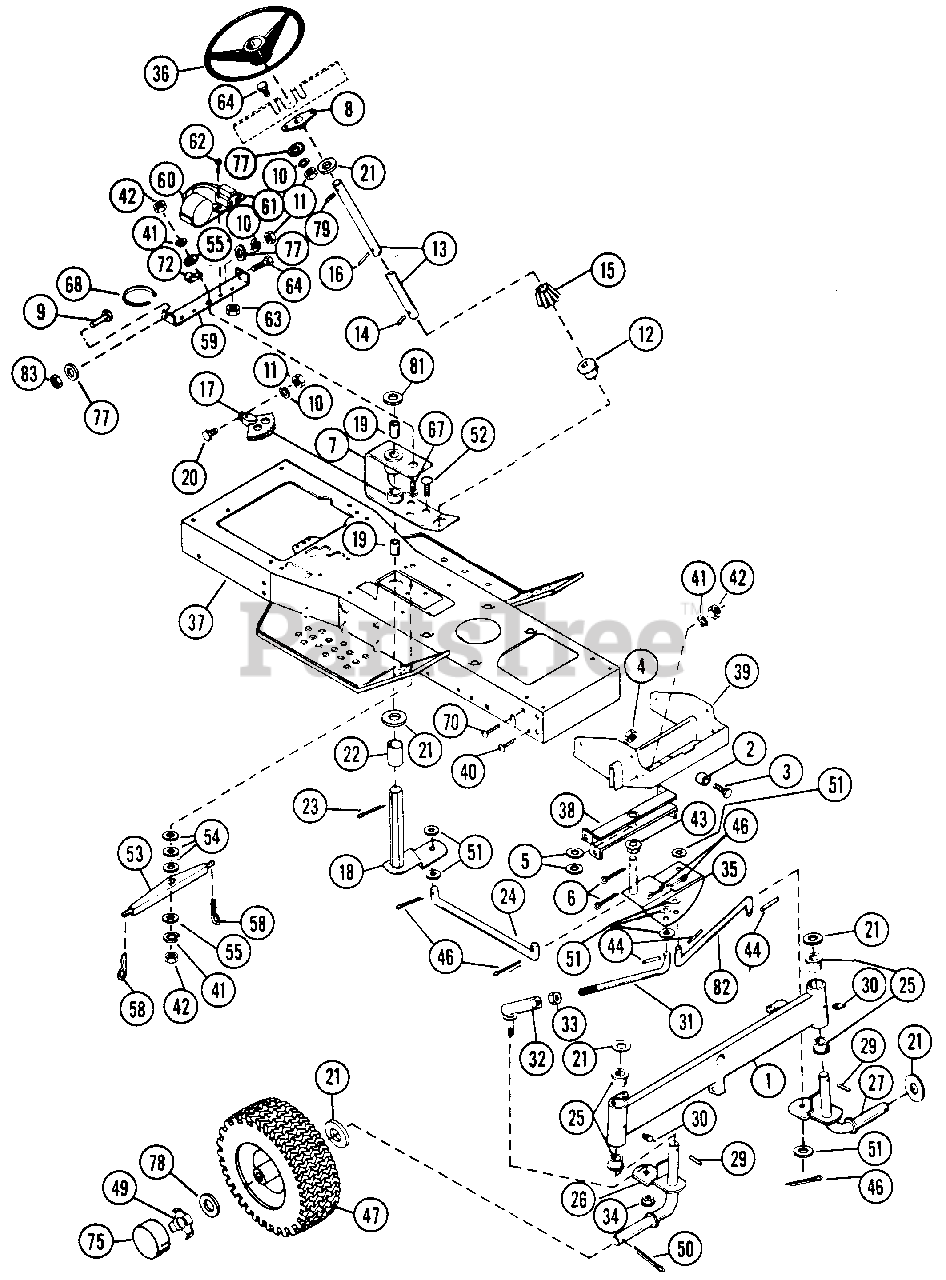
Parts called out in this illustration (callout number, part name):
1	FRONT AXLE ASSEMBLY
2	SPACER
3	BOLT, HEX 1/2-13X1.25
4	NUT, LOCK 1/2-13
5	WASHER, FLAT .656X1.312X.095
6	PIN, COTTER .125X1.25
7	STEERING BRACKET
8	FLANGE BEARING
9	BOLT, HEX 5/16-18X1.25
10	WASHER, LOCK 3/8 SP HEAVY
11	NUT, HEX 5/16-18
12	FLANGE BUSHING
13	STEERING COLUMN
14	PIN
15	PINION GEAR, STEERING
16	PIN, SPRING .187X1.250
17	STEERING BEVEL GEAR
18	ARM AND SHAFT
19	SLEEVE BUSHING
20	BOLT, HEX 5/16-18X1.75
21	WASHER, FLAT .938X1.750X.134
22	SPACER
23	PIN, COTTER .187X1.25
24	STEERING LINK
25	FLANGE BUSHING
26	R. H. SPINDLE
27	L. H. SPINDLE
29	PIN, SPRING .250X1.500
30	SPIN DRIVE ZERK FITTING
31	DRAG LINK
32	BALL JOINT
33	NUT, HEX 1/2-20
34	NUT, LOCK 1/2-20
35	STEERING PIVOT
36	STEERING WHEEL
38	STEERING PIVOT CHANNEL
39	FRONT AXLE SUPPORT
40	BOLT, CARRIAGE 3/8-16X.75
41	WASHER, LOCK 3/8 REG.
42	NUT, HEX 3/8-16
43	FLANGE BUSHING
44	PIN, SPRING .125X1.000
46	PIN, COTTER .125X1.00
47	TIRE AND WHEEL ASSEMBLY
49	SPINDLE CUP
50	PIN, COTTER TEE HD. 1/4
51	WASHER, FLAT .56X.187X.109
52	BOLT, 3/8-16X1.25 RD HD SQ NK
53	PIVOT ARM
54	WASHER, .626 IDX3.85 ODX21 GA
55	WASHER, FLAT .406X.812X.065
58	HAIR PIN, INTERNAL 3/32
59	BRACE
60	MODULE(W/CONNECTOR)
61	CONNECTOR
62	SCREW, MACHINE 10-24X.625
63	NUT, KEPS 10-24
64	BOLT, HEX 5/16-18X.75
67	BOLT, HEX 3/8-16X1.00
68	TIE DOWN
70	BOLT, 3/8-16X1.00 RD HD SQ NK
72	CLIP
75	HUB CAP
77	WASHER, FLAT .312X.734X.065
78	WASHER, FLAT .938X1.750X.134
79	PIN, SPRING .250X1.750
81	WASHER
82	DRAG LINK
83	NUT, LOCK 5/16-18
